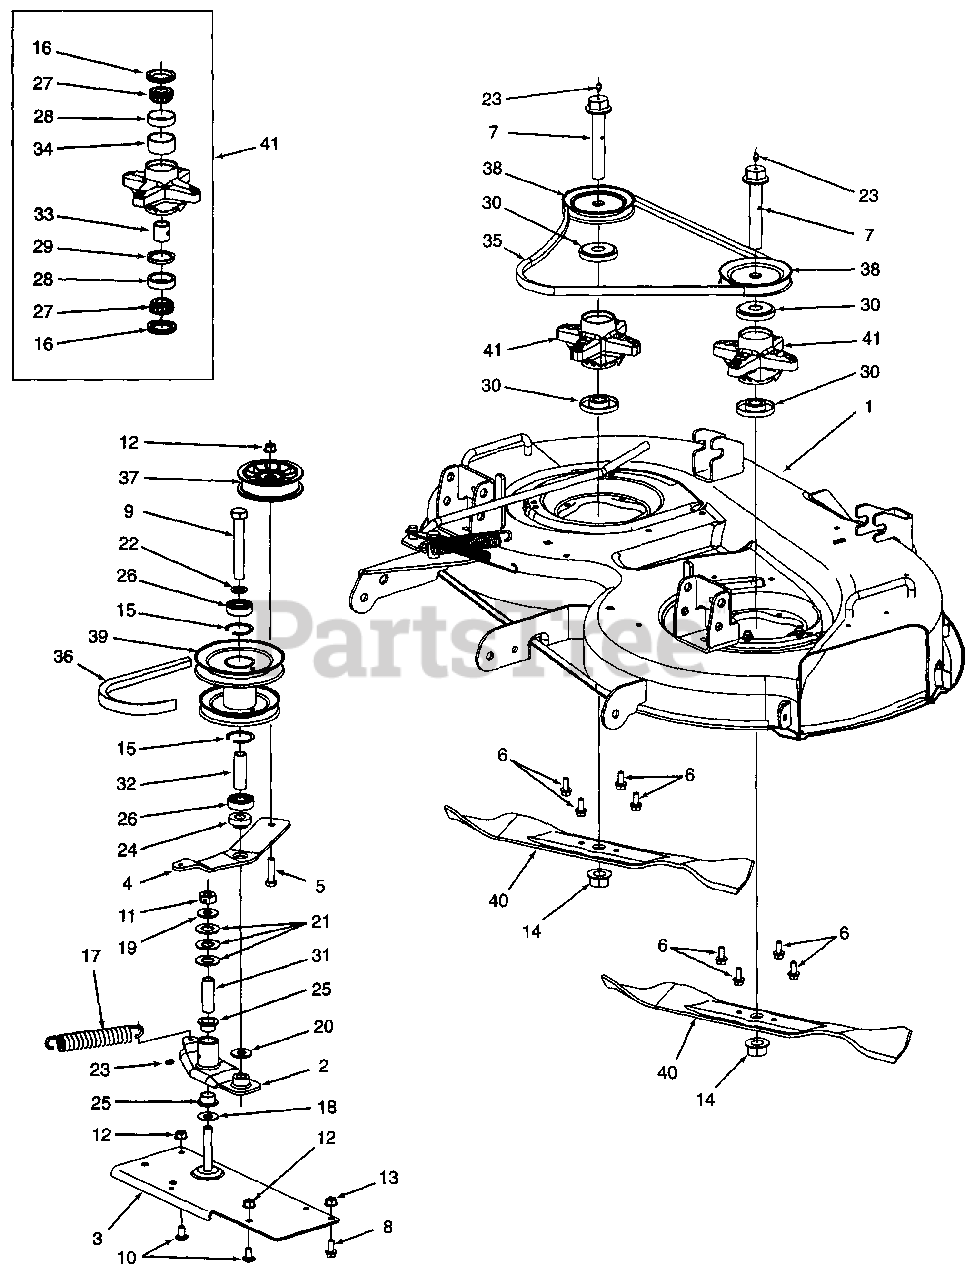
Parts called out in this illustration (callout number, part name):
6	Screw, Hex Wash Hd TT Tapp 5/16-18 x .75
7	Bolt, Spindle, 3/4-16 x 4.25
8	Screw, Hex Cap, 5/16-18 x .75 GR5
9	Screw, Hex Cap, 5/16-18 x 4.25 GR5
10	Bolt, Carriage, 3/8-16 x .75
11	Nut, Hex Center Lock, 1/2-20
12	Nut, Hex Flange Lock, 3/8-16
13	Nut, Hex Flange Lock, 5/16-18
14	Nut, Hex Flange, 3/4-16
15	Ring, Internal Snap
16	Seal, Oil. 1.25 x 1.874 x .25
17	Spring, Extension, 1.0 OD x 6.14
18	Washer, Flat, .513 x 1.25 x .036
19	Washer, Flat, .5 x 1.25 x .10
20	Washer, Flat, .64 x 1.24 x .06 Hdn
21	Washer, Flat, .76 x 1.49 x .06 Hdn
22	Washer, Flat, 5/8 x 1.0 x .063
23	Fitting, 3/16 Drive Lube
24	Spacer, Shoulder
25	Bearing, Flange, 3/4 ID x .52
26	Bearing, Ball, .625 x 1.57 x .47
27	Cone, Bearing
28	Cup, Bearing
29	Spacer, Bearing
30	Spacer, Deck Spindle
31	Spacer, .50 x. 75 x 2.25
32	Spacer, .635 x 2.0
33	Spacer, Bearing, .78 x .963 x .7777
34	Spacer, Bearing 1.615 x 1.86 x .8427
35	Belt, Spindle, A-Section x 63.2
36	Belt, PTO, B-Section x 69
37	Pulley, Flat Idler, 3.5 OD
38	V-Pulley, 4.0 Dia
39	Pulley, Double 5.0 OD x 5.56 OD
40	Blade, 3 in One, 21.20 Lg
41	Spindle Assembly, Blade
